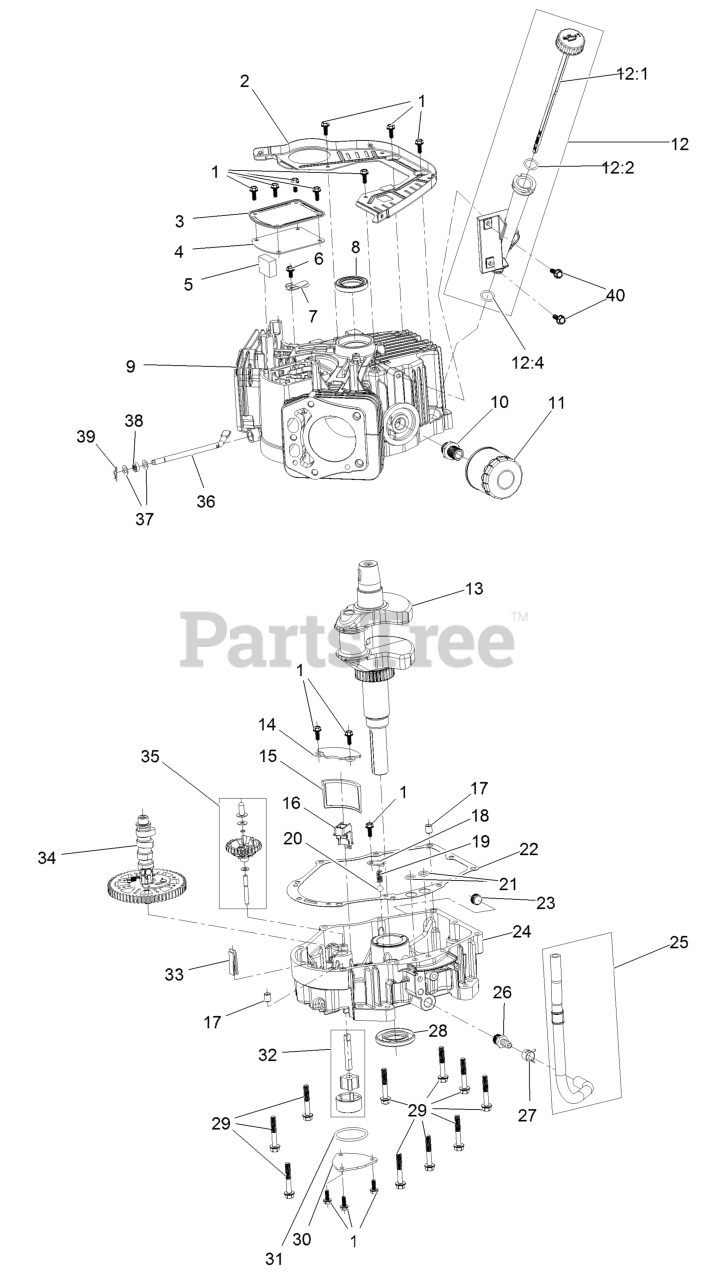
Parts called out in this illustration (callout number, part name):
1	SCREW-HHF
3	COVER-BREATHER
4	GASKET-BREATHER
5	FILTER-BREATHER
6	SCREW-HHF
7	VALVE-BREATHER
8	SEAL-OIL
9	CRANKCASE
12	OIL TUBE ASM
12:1	DIPSTICK
13	CRANKSHAFT
14	COVER-SCREEN, OIL
15	SCREEN-OIL
16	RETAINER-SCREEN
17	PIN-DOWEL
18	PLATE-RETAINER
20	VALVE-BALL
22	GASKET-COVER, CRANKCASE
23	PLUG-DRAIN
24	COVER-CRANKCASE
25	OIL DRAIN HOSE ASM
26	FITTING-HOSE
27	CLAMP-HOSE
29	SCREW-HHF
30	COVER-OIL PUMP
32	OIL PUMP ASM
33	DEFLECTOR-OIL, RUBBER
36	SHAFT-GOVERNOR
37	WASHER-PLAIN
38	SEAL-OIL
39	PIN-HAIR
40	SCREW-HHF
